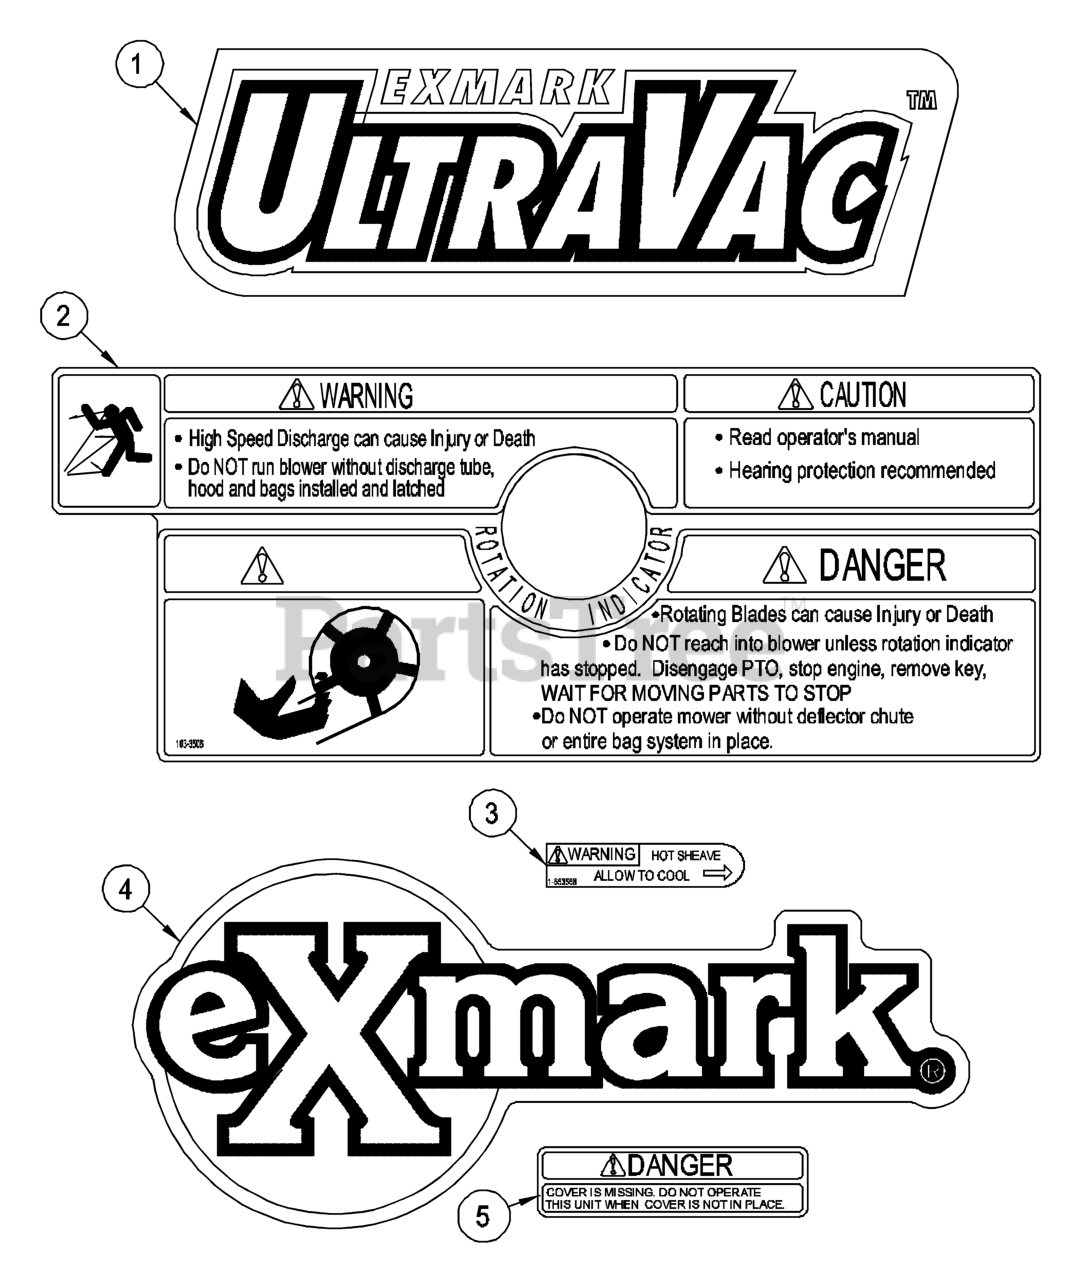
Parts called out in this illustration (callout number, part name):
1	DECAL, ULTRAVAC
2	DECAL-WARNING
3	DECAL, EXMARK LOGO
4	DECAL-WARNING
5	DECAL-COVER, MISSING
